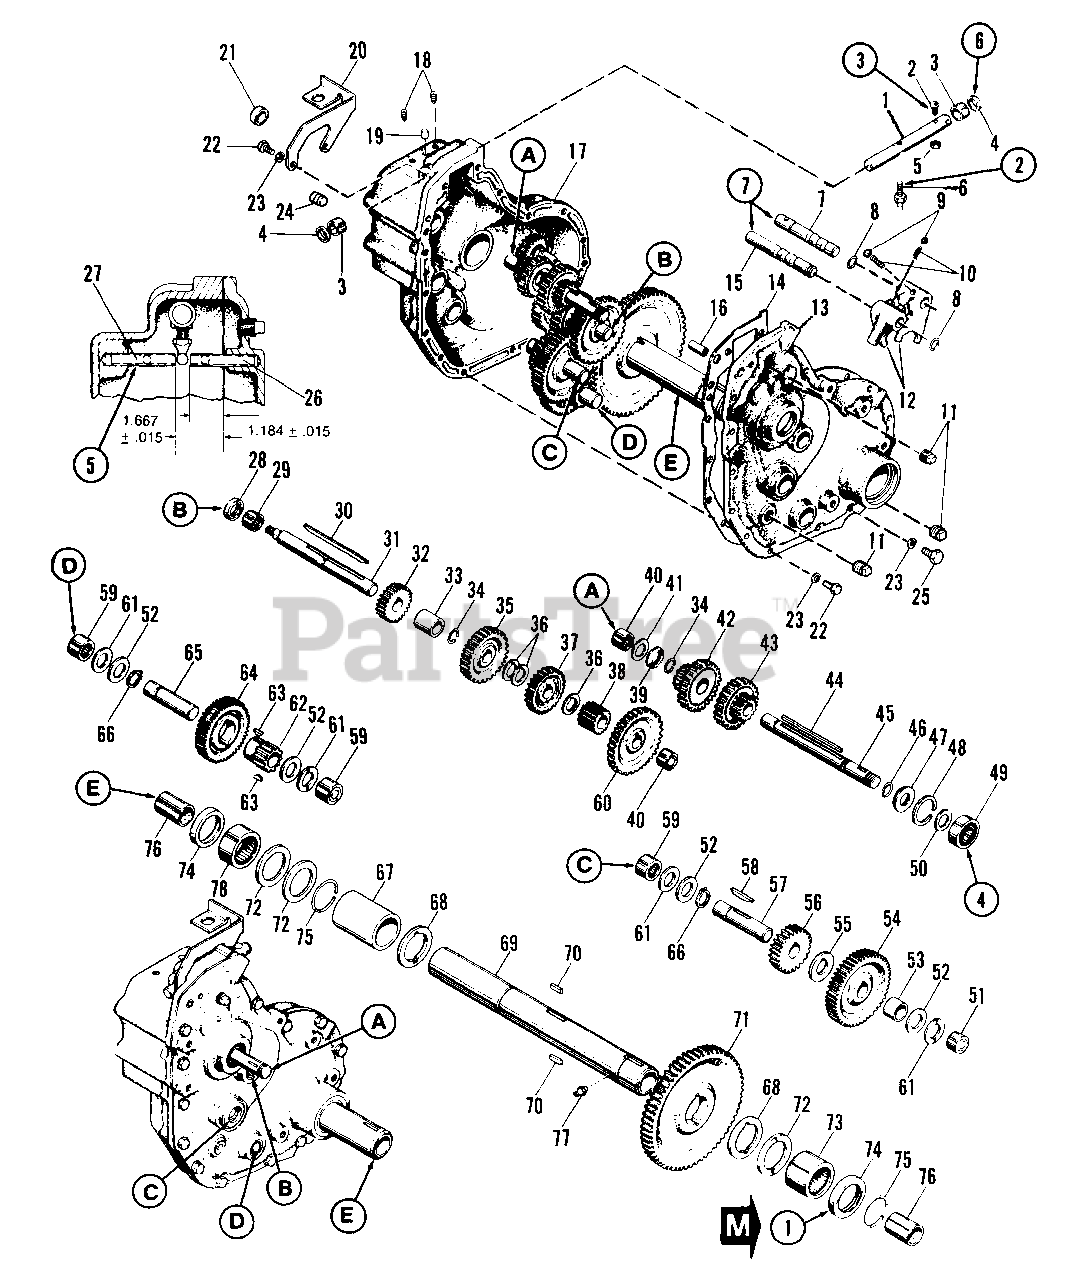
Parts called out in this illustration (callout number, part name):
1	ROD, Shift
2	BOLT, Carriage, Special
3	SPACER, Differential
5	LOCKNUT, Hex, Jam, 5/16-18
6	STEM, Shift
7	SHAFT, Shift, Hi-Lo
8	RING, Retaining
9	BALL, Shiftlock
11	PLUG, Pipe, 3/8
12	FORK, Shift
13	COVER ASSY., Gear Case
14	GASKET, Gear Case
15	SHAFT, Shifter, Rev.-Med.
16	PIN, Roll, 3/8 x 1
17	CASE ASSY., Gear
18	SETSCREW, 5/16-18 x 1/2
20	SUPPORT, Switch
21	PLUG, Expansion
22	CAPSCREW, Hex Hd., 5/16-18 x 1
23	LOCKWASHER, 5/16
24	SETSCREW, 3/8-16 x 3/8
25	CAPSCREW, Hex Hd., 5/16-18 x 1-1/2
26	PIN ASSY., Roll
27	PIN ASSY., Rev. Gear
29	BEARING, Needle
31	SHAFT, 1st Intermediate
32	* PINION, Reverse & IV
34	RING, Retaining
35	GEAR, Driven, II
37	PINION, Driven, III
38	PINION, 1st Intermediate
40	BEARING, Needle
42	GEAR ASSY.
45	SHAFT, Pulley
46	RING, Retaining
48	RING, Retaining
49	BEARING, Ball
51	BEARING, Needle
54	GEAR, 2nd Intermediate
56	PINION, 2nd Intermediate
57	SHAFT, 2nd intermediate
59	BEARING, Needle
60	GEAR, Driven, I
62	PINION, 3rd Intermediate
63	KEY, Woodruff, #6
64	GEAR, 3rd Intermediate
65	SHAFT, 3rd Intermediate
66	RING, Retaining
67	SPACER, Axle Tube
68	WASHER, Axle Tube
69	TUBE & BUSHING ASSY.
71	GEAR, Drive
73	BEARING, Needle
78	BEARING, Needle
79	OIL SEAL REPLACEMENT KIT (Includes Ref. Nos. 4, 14, 28 & 74)
